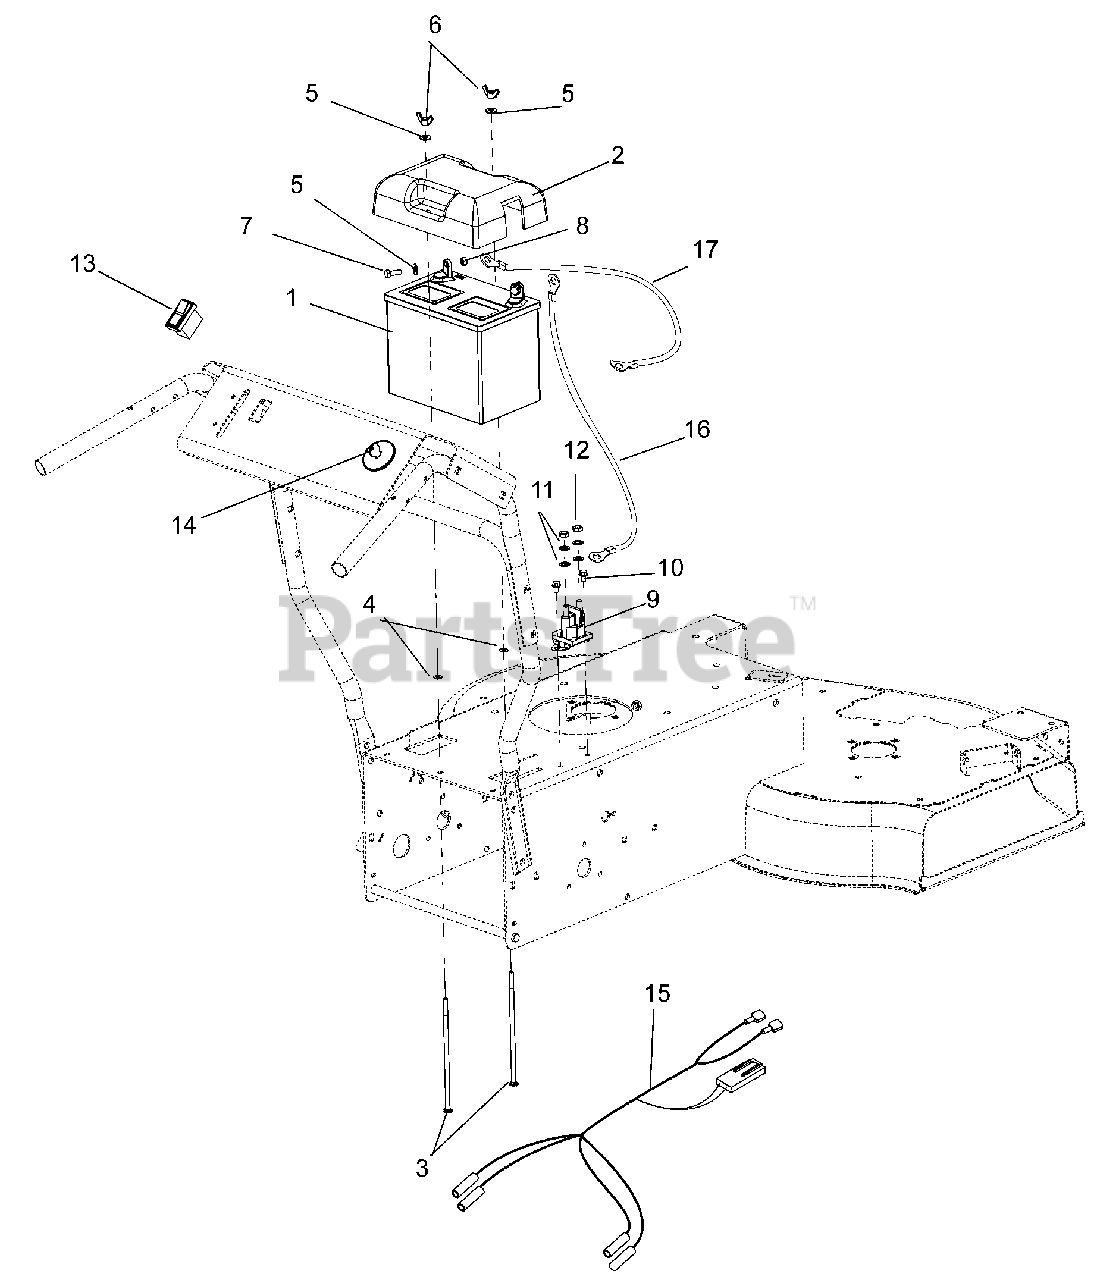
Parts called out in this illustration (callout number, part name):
1	Battery, SLI U1B-165
2	Cover, Battery
3	Bolt, Round Head Square Neck .25-20 x 7.00 Grade 2
4	Nut, Push .25 x .50 O.D.
5	Washer, Flat Steel .281 x .62 x .065
6	Nut, Locking Wing .250-20
7	Bolt, Hex .25-20 x .75
8	Nut, KEPS .250-20
9	Solenoid, HP RTV
10	Screw, Tapping Hex Washer Head .250-20 x .37
11	Washer, Internal Lock .31
12	Nut, Jam .31-24
13	Switch, Rocker
14	Switch, Ignition Key, 3 Position
15	Harness, Wiring
16	Cable, Starter 6.75"
17	Cable, Ground
